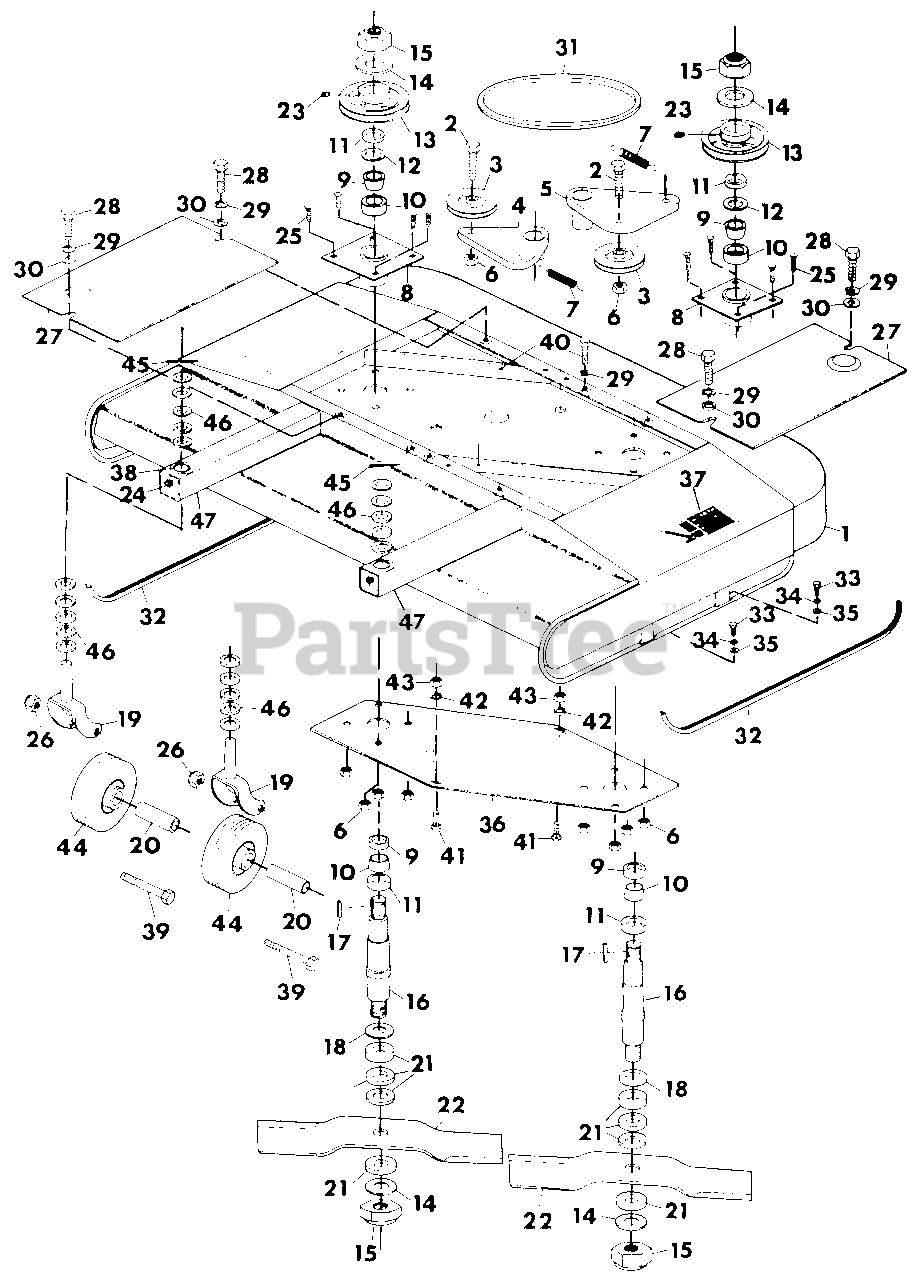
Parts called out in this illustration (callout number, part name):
1	WELDMENT, DECK
2	BOLT, HEX 3/8-16X1.50
3	IDLER
4	WELDMENT, ARM IDLER PIVOT
5	IDLER, PIVOT ARM
6	NUT, LOCK 3/8-16
7	SPRING
8	HOUSING, SPINDLE BEARING WELDMENT
9	CONE, ROLLER BEARING
10	CUP, ROLLER BEARING
11	SEAL, OIL
12	RING, SEAL
13	PULLEY, ROTOR
14	WASHER, FLAT .969X2.250X.165
15	NUT, LOCK 7/8-9
16	SHAFT, ROTOR
17	KEY, SQUARE .25X1
18	SHIELD, DUST
19	WELDMENT, CASTER FORK
20	BUSHING
21	COLLAR, BLADE SPACER(.25 INCH)
22	BLADE, MOWER
23	SCREW, SET 5/16-18X.38
24	FITTING, LUBE 1/4-28
25	BOLT, 3/8-16X1.00 RD HD SQ NK
26	NUT, LOCK 1/2-13
27	COVER, BELT
28	BOLT, HEX 3/8-16X.62
29	WASHER, LOCK 3/8 REG.
30	WASHER, FLAT .406X.812X.065
31	BELT, DRIVE
32	SKID
33	BOLT, HEX 5/16-24X.875
34	WASHER, LOCK 5/16
35	WASHER, FLAT .344X.81X.065
36	SUPPORT, DECK WELDMENT
37	DECAL, DANGER FOOT
38	BEARING, BRONZE
39	BOLT, HEX 1/2-13X3.75
40	BOLT, HEX 3/8-16X1.00
41	BOLT, 1/2-13X3.00 RD HD SQ NK
42	WASHER, LOCK 1/2
43	NUT, HEX 1/2-13
44	WHEEL, CASTER
45	PIN, COTTER .125X1.50
46	WASHER, FLAT .812X1.496X.134
47	SUPPORT, GAUGE WHEEL
